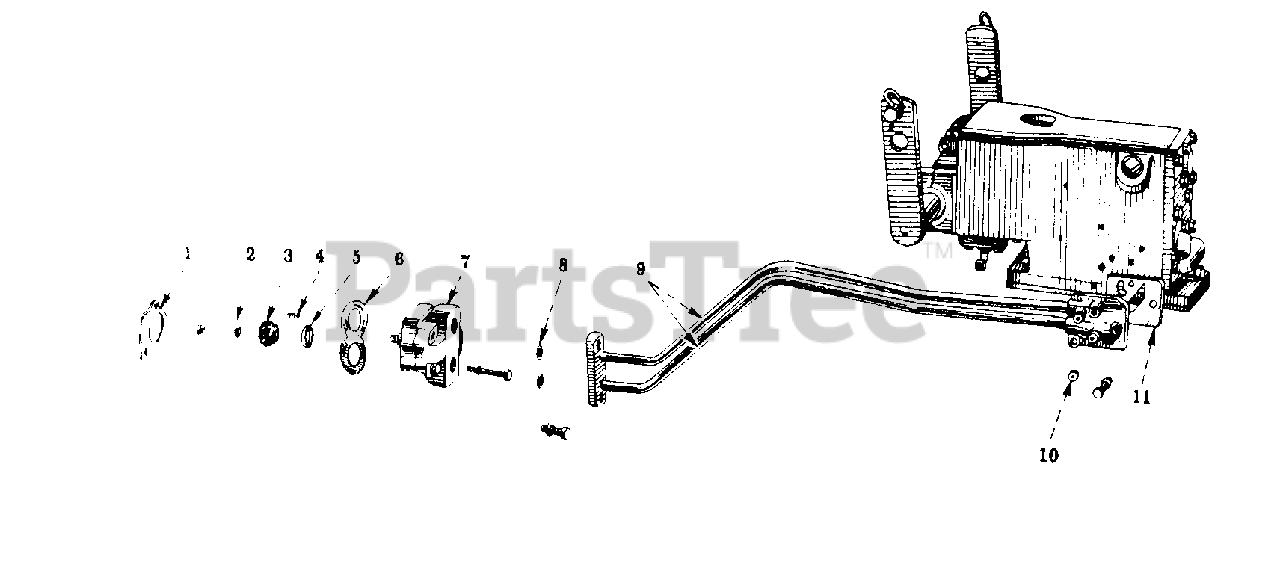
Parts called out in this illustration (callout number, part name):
1	GASKET, TOUCH-CONTROL PUMP
2	WASHER, TOUCH-CONTROL PUMP DRIVE GEAR
3	GEAR, TOUCH-CONTROL PUMP DRIVE -10 T-
4	KEY, 1/8 X 1/2 WOODRUFF NO 3
5	O-RING, 1/2 X 11/16 X 3/32 -SHAFT SEAL-
6	SPRING, BEARING COVER
7	PUMP ASSY, HYDRAULIC TOUCH-CONTROL
8	O-RING, 11/16 X 7/8 X 3/32
9	MANIFOLD ASSY, HYDRAULIC LIFT TUBE
10	PLUG, 1/8-27 AUTO SQ-HD PIPE
11	GASKET, MANIFOLD FLANGE
